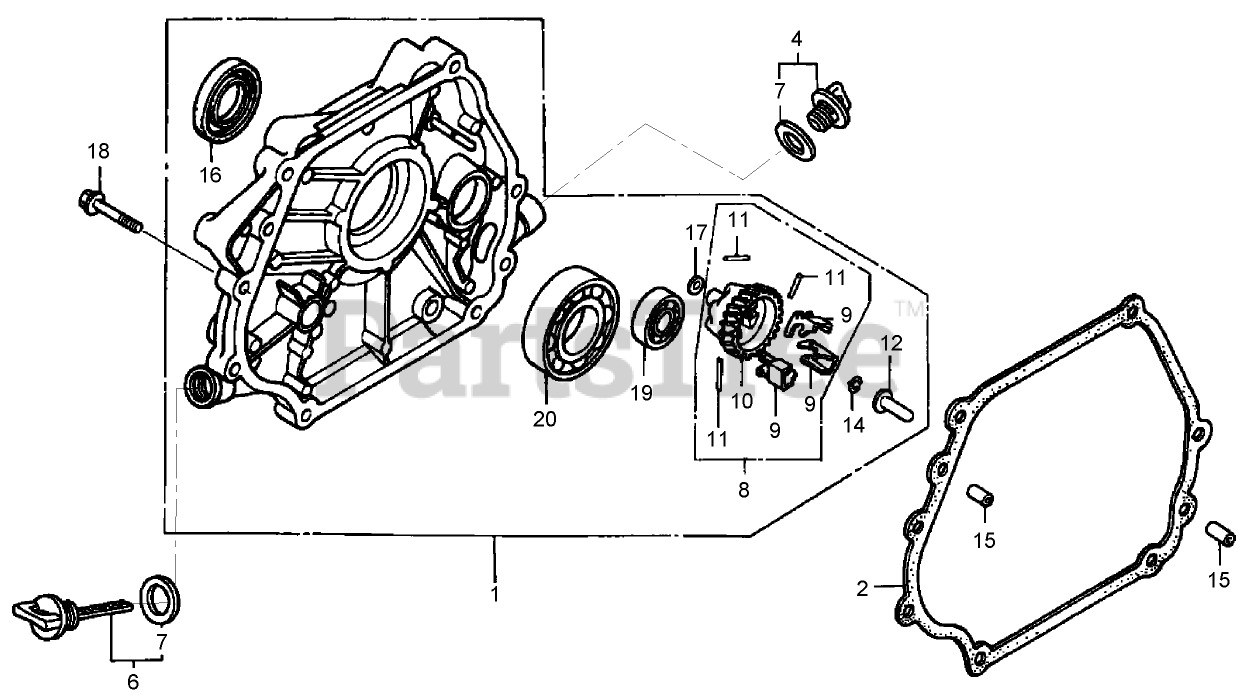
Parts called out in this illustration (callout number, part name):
1	COVER ASM-CRANKCASE
2	GASKET-CASE COVER
4	CAP ASM-OIL FILLER
6	CAP ASM-OIL FILLER
7	GASKET-CAP, OIL FILLER
8	GOVERNOR ASM
9	WEIGHT-GOVERNOR
10	HOLDER-GOVERNOR WEIGHT
11	PIN-WEIGHT, GOVERNOR
12	SLIDER-GOVERNOR
14	CLIP-HOLDER, GOVERNOR
15	PIN-DOWEL
16	SEAL-OIL (35X5X8)
17	WASHER-PLAIN (6MM)
18	BOLT-FLANGE (8X40)
19	BEARING-RADIAL BALL
20	BEARING-BALL, RADIAL
